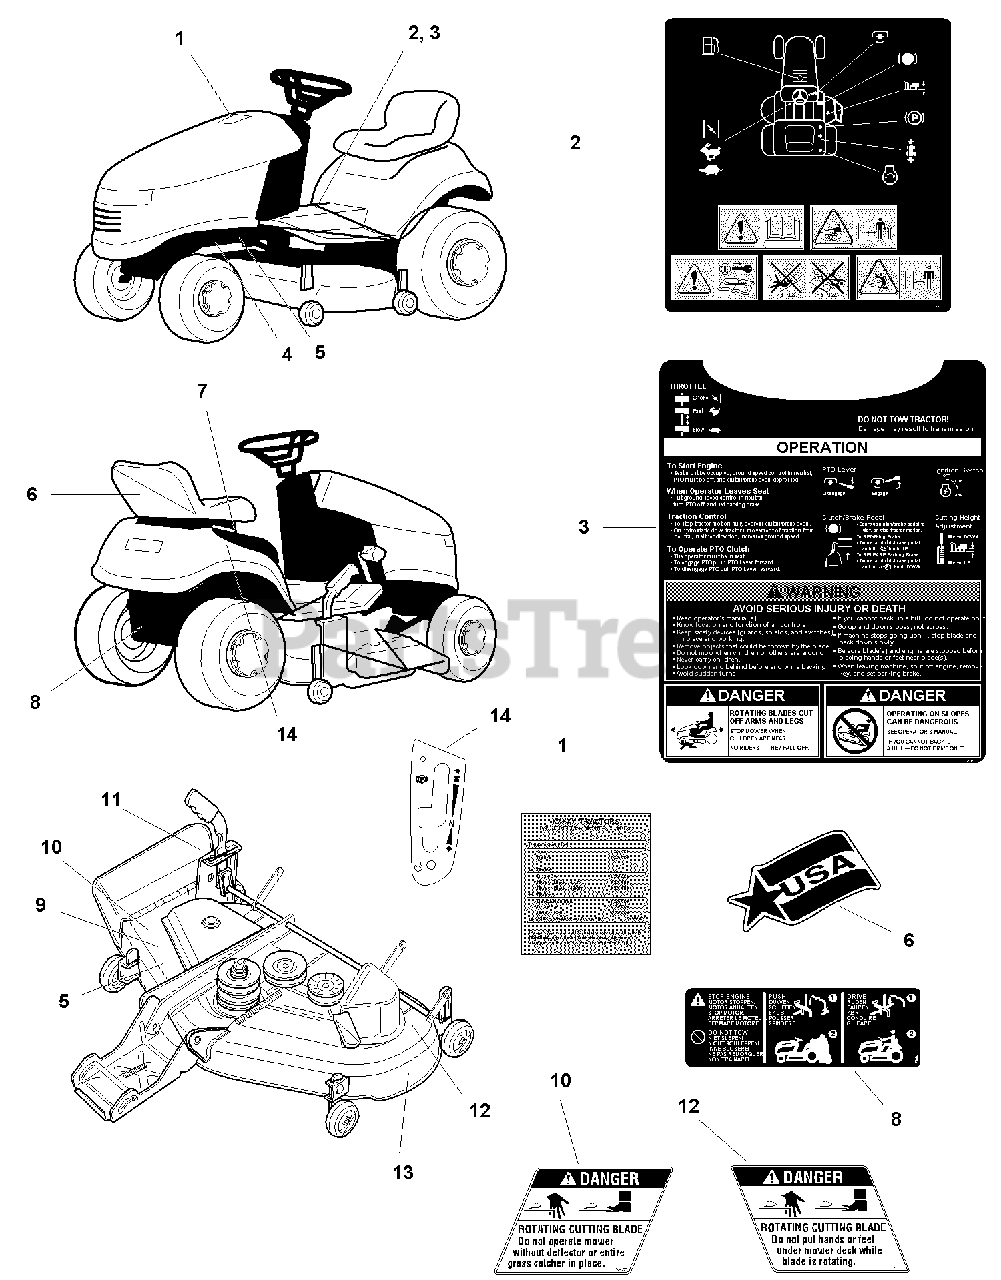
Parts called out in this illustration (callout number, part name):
1	DECAL, Belts & Mower Blades
2	DECAL, Operating Instructions
3	DECAL, Operating Instructions
4	DECAL, Patent (Not Serviced)
5	DECAL, OPEI (Not Serviced)
5	DECAL, Serial Number (Not Serviced)
5	DECAL, CE & Serial Number Export (Not Serviced)
6	DECAL, USA Logo
7	DECAL, PTO Control Symbols
8	DECAL, Transmission Release Valve
10	DECAL, DANGER
11	DECAL, Height of Cut
12	DECAL, DANGER
12	DECAL, Danger Symbol
13	DECAL, Free Floating Mower
14	DECAL, Shift Hydro
